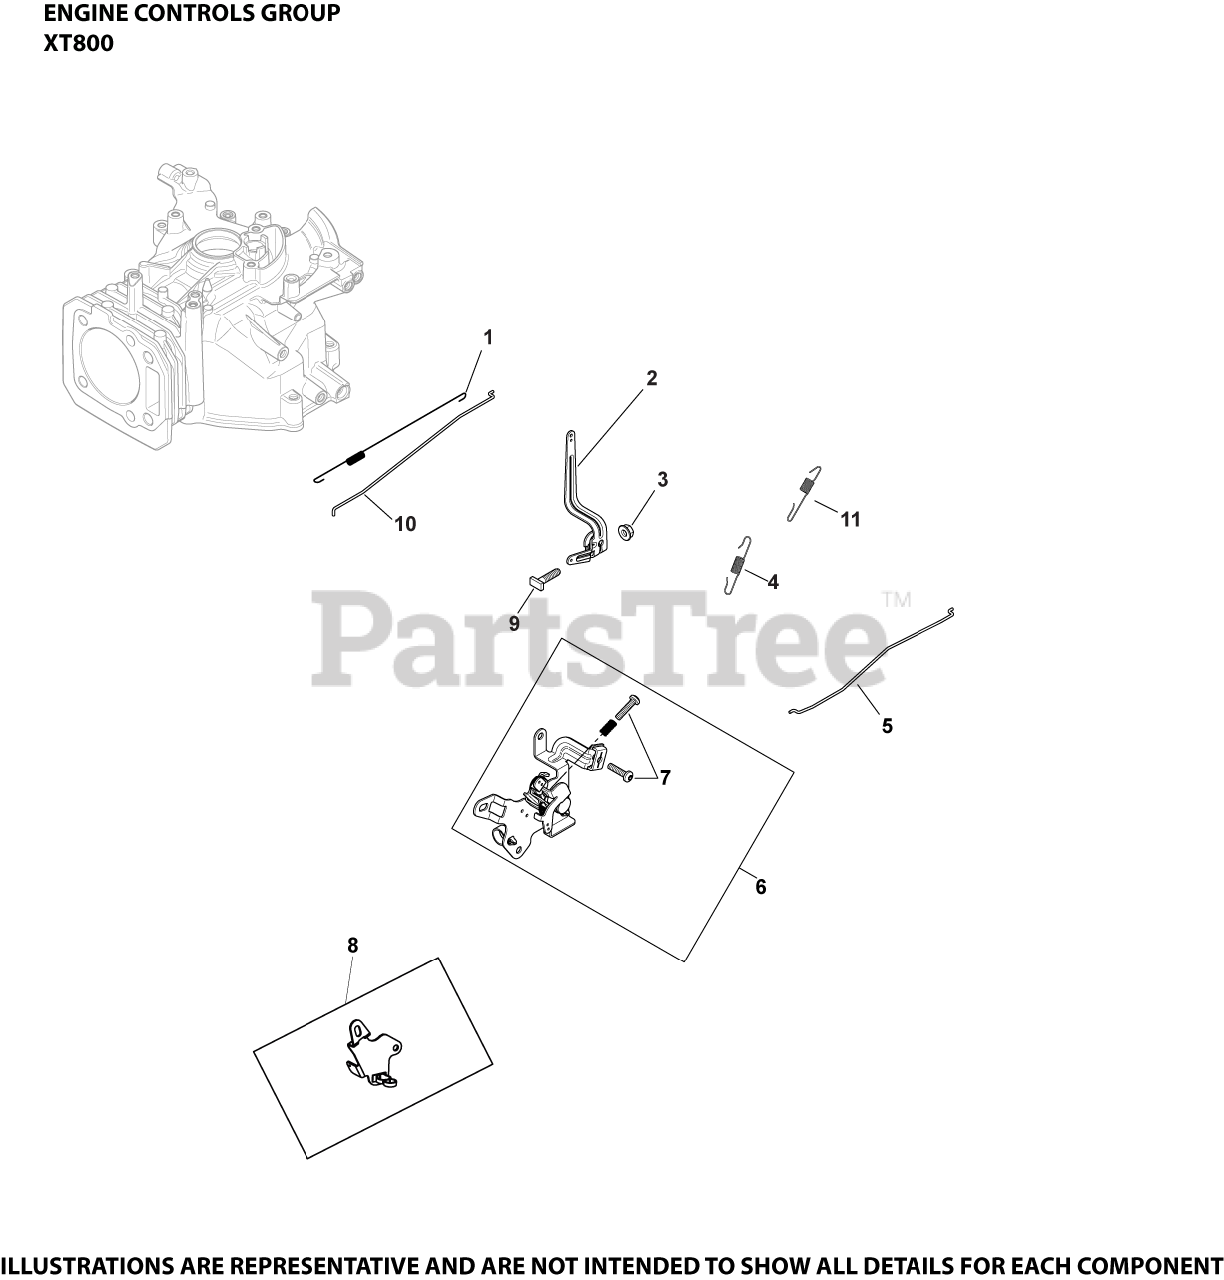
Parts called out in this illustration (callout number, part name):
1	SPRING, LINKAGE
2	LEVER, GOVERNOR-USE 14 090 37-S
3	NUT, HEX FLANGE (M6) - USE 14 100 16-S
4	SPRING, GOV (2800-3300 RPM)
5	LINKAGE, CHOKE
6	CONTROL ASSEMBLY (VAR. SPEED) USE 14 536 18-S
7	SCREW, #25 6-LOBE PAN HD (M5)
9	SCREW, RECTANGLE HEAD (M6)
10	LINKAGE, GOVERNOR
